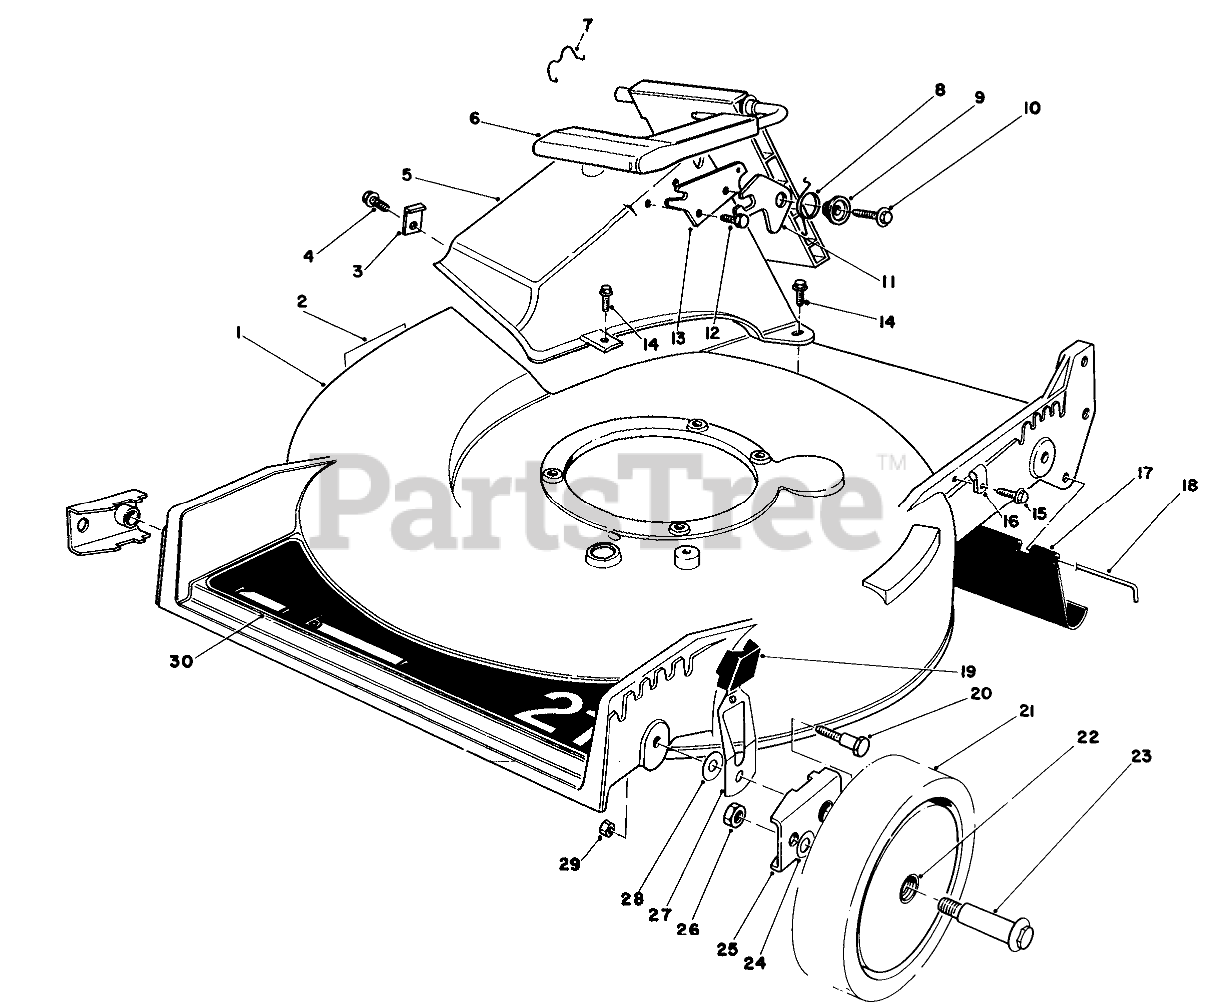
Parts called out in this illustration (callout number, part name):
1	21HP RB-SUZ HSG/DECAL
2	DECAL-DANGER
3	TUNNEL CLIP
4	SCREW
5	Tunnel Discharge
6	Discharge Door Assembly
7	DOOR RET SPRING
8	TORSION SPRING
9	DOOR SPACER
10	SCREW-HWH
11	SAFETY LATCH
12	SCREW-PLASTITE
13	DOOR LATCH PLATE
14	SCREW-HWH
15	SCREW
16	CLAMP-CABLE
17	SHIELD-TRAILING
18	ROD-SHIELD
19	KNOB-ARM
20	PIVOT SCREW
21	Wheel & Tire Assembly (Incl. Ref. #22)
22	BUSHING
23	WHEEL BOLT
24	WASHER
25	HP PIVOT ARM ASM
26	NUT-LOCK
27	Spring Arm
28	WASHER-PIVOT
29	NUT-LOCK, NI
30	DECK DECAL
